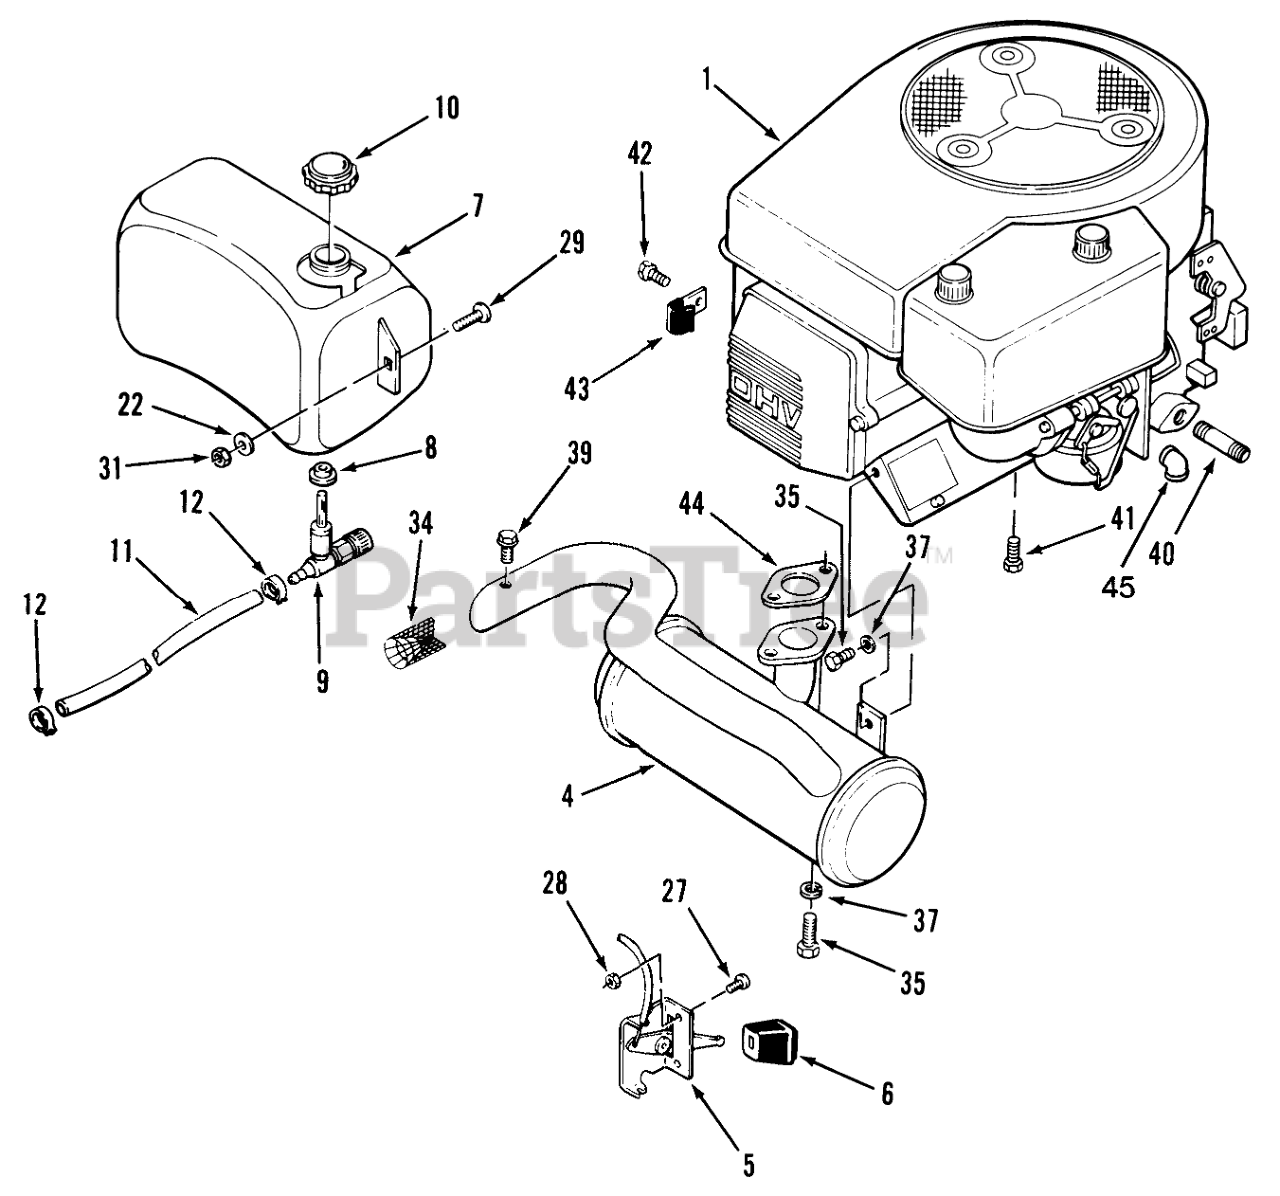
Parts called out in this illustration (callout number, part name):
1	Engine-12HP-B & S Model 281707-0226-01 Model 212-HA
4	MUFFLER-EXHAUST
5	CONTROL-THROTTLE
6	KNOB-CONTROL
7	Fuel Tank
8	BUSHING
9	VALVE-FUEL
10	CAP GAS
11	Line-Fuel
12	Clamp
19	HHCS
20	Nut
22	WASHER 5/16 SAE
24	Bolt
26	Nut
27	Screw
28	Nut
29	Bolt
31	Nut
32	Elbow 90deg. 3/8
34	Arrester-Spark
35	HHCS M8X1.25X20
37	Lockwasher
39	BOLT-HEX S.T. #8X1/2
40	Pipe
41	Bolt
42	HHCS M8X1.25X20
43	J-CLIP
44	GASKET-EXHAUST
45	ELBOW 3/8 90 DEG
